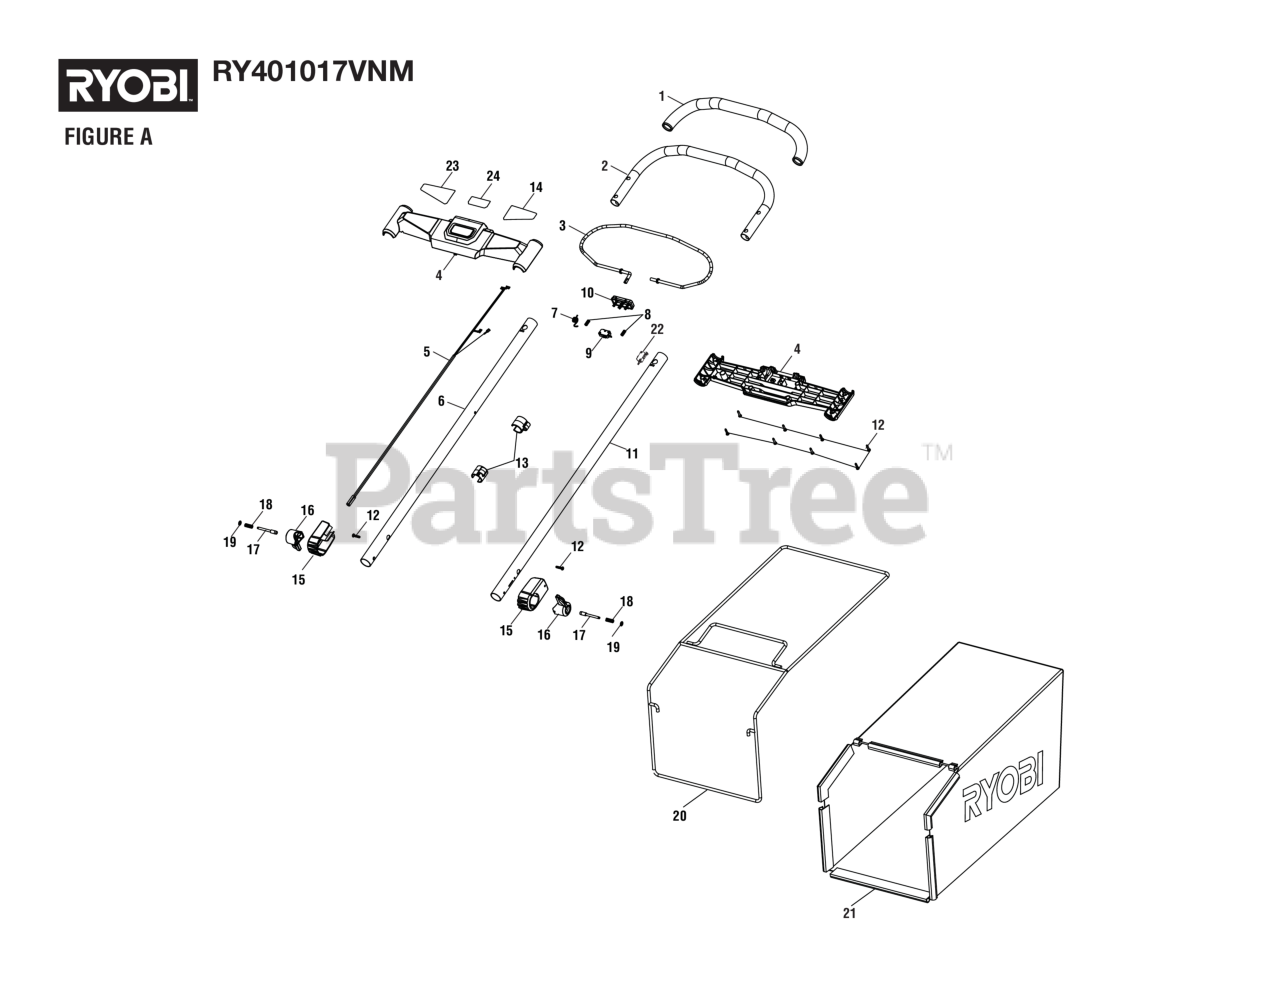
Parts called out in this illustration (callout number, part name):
1	Handle Foam
4	Upper Handle Assembly
5	Wire Assembly
6	Lower Tube
7	Bail Reset Spring
9	On/Off Switch
9	Micro On/Off Switch (6A)
10	Start Button
11	Lower Tube
12	Screw (M4 x 18 mm, T20 Torx Pan Hd.)
13	Cord Retainer
14	Upper Handle Label (Right)
15	Adjustment Knob Bushing
16	Adjustment Knob
17	Detent Pin
18	Compression Spring
19	Retaining Ring
20	Grass Catcher Frame
21	Grass Catcher
23	Upper Handle Label (Left)
24	Logo Label
